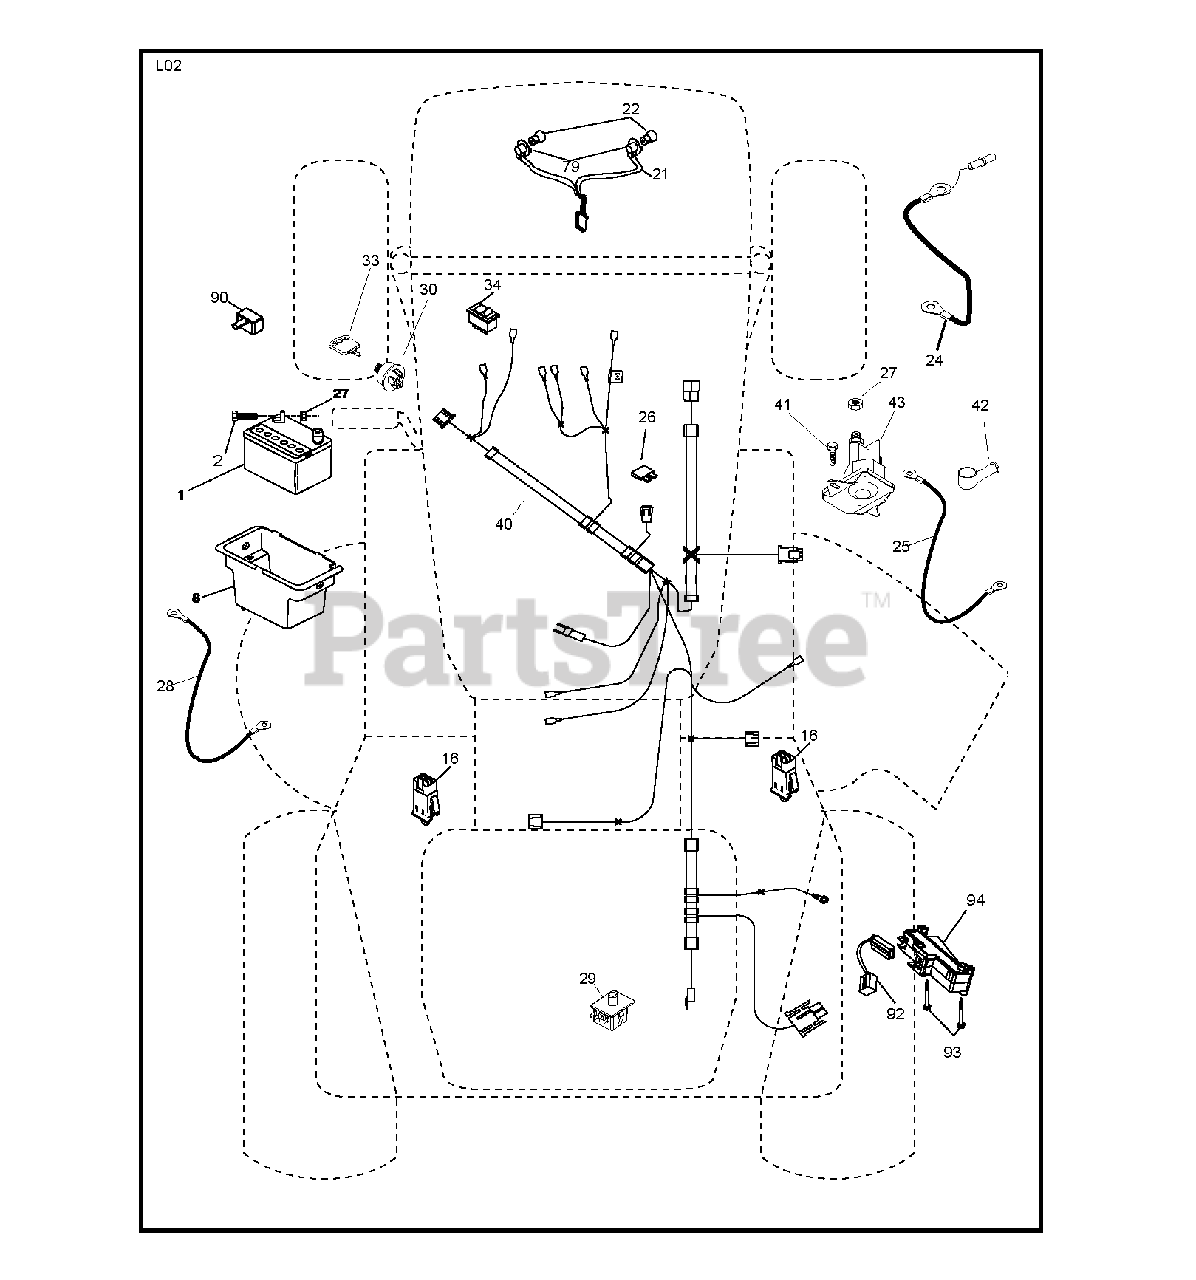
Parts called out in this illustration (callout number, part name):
1	REPL BY 532 12 38-99
8	BOX.BATTERY.FENDER
16	SWITCH INTERLOOK PUSH-IN
21	HARNESS ASSY LIGHT
22	LIGHTBULB
24	BATTERY CABLE GT
25	CABLE BATTERY
26	FUSE 20AMP
27	NUT
28	CABLE T
29	SWITCH.SEAT.DP W/RAMPS
30	SWITCH.IGN.DELTA.W.LGH.ROS
33	KEY.CHAIN.BLISTER.PACK.GEN.INT
34	SWITCH LT
40	HARNESS.IGN.CABLE.REG.
42	TERMINAL COVER
43	SOLENOID.W/BRASS.PLUNG
79	BULB HOLDER ASM.
90	COVER TERMINAL
92	HARNESS.PIGTAIL.CONSLE
93	SCREW.PLASTITE
94	MODULE.REVERSE.ROS
